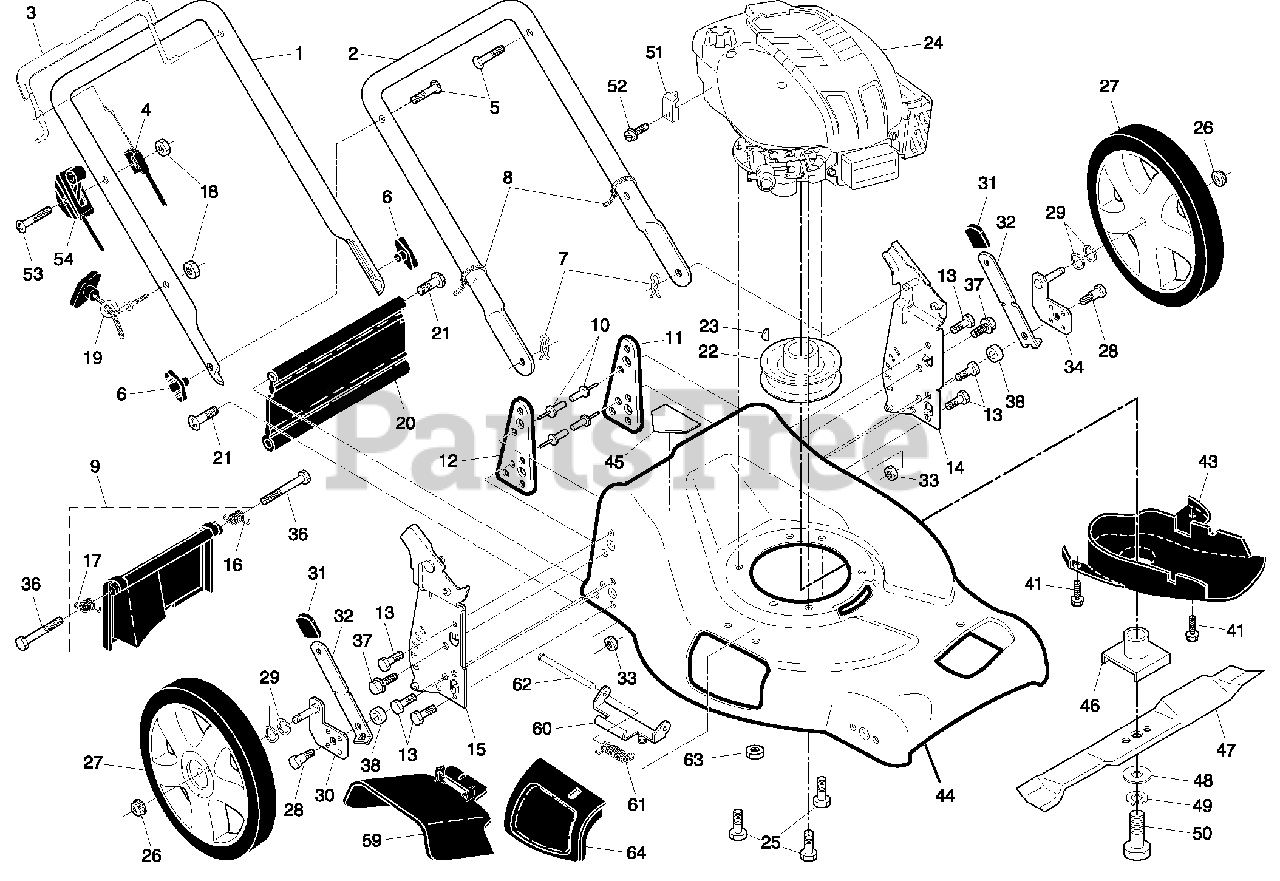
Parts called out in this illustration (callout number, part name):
1	Control Cable Assembly
2	Bearing, Wheel Adjuster
3	Pan Head Tapping Screw #10-24 x 2-3/4
4	Hex Washer Head Screw 1/4-20 x 2.12
5	V-Belt
6	Spring Retainer
7	Nut, Hex, Flanged 1/4-20
8	Hubcap
9	Locknut
11	Wheel & Tire Assembly
12	E-Ring
13	Pinion
14	Dust Cover
16	Washer 1/2
18	Selector Knob
28	Drive Cover
31	Nut, Hex, Flanged
32	Drive Pulley
35	Kit, Wheel Adjuster, LH
36	Gear Case Assembly (See Breakdown)
38	Locknut 1/4-20
40	Spring
41	Kit, Wheel Adjuster, RH
54	Grassbag Assembly
55	Driveshaft Cover
57	Frame, Grassbag
